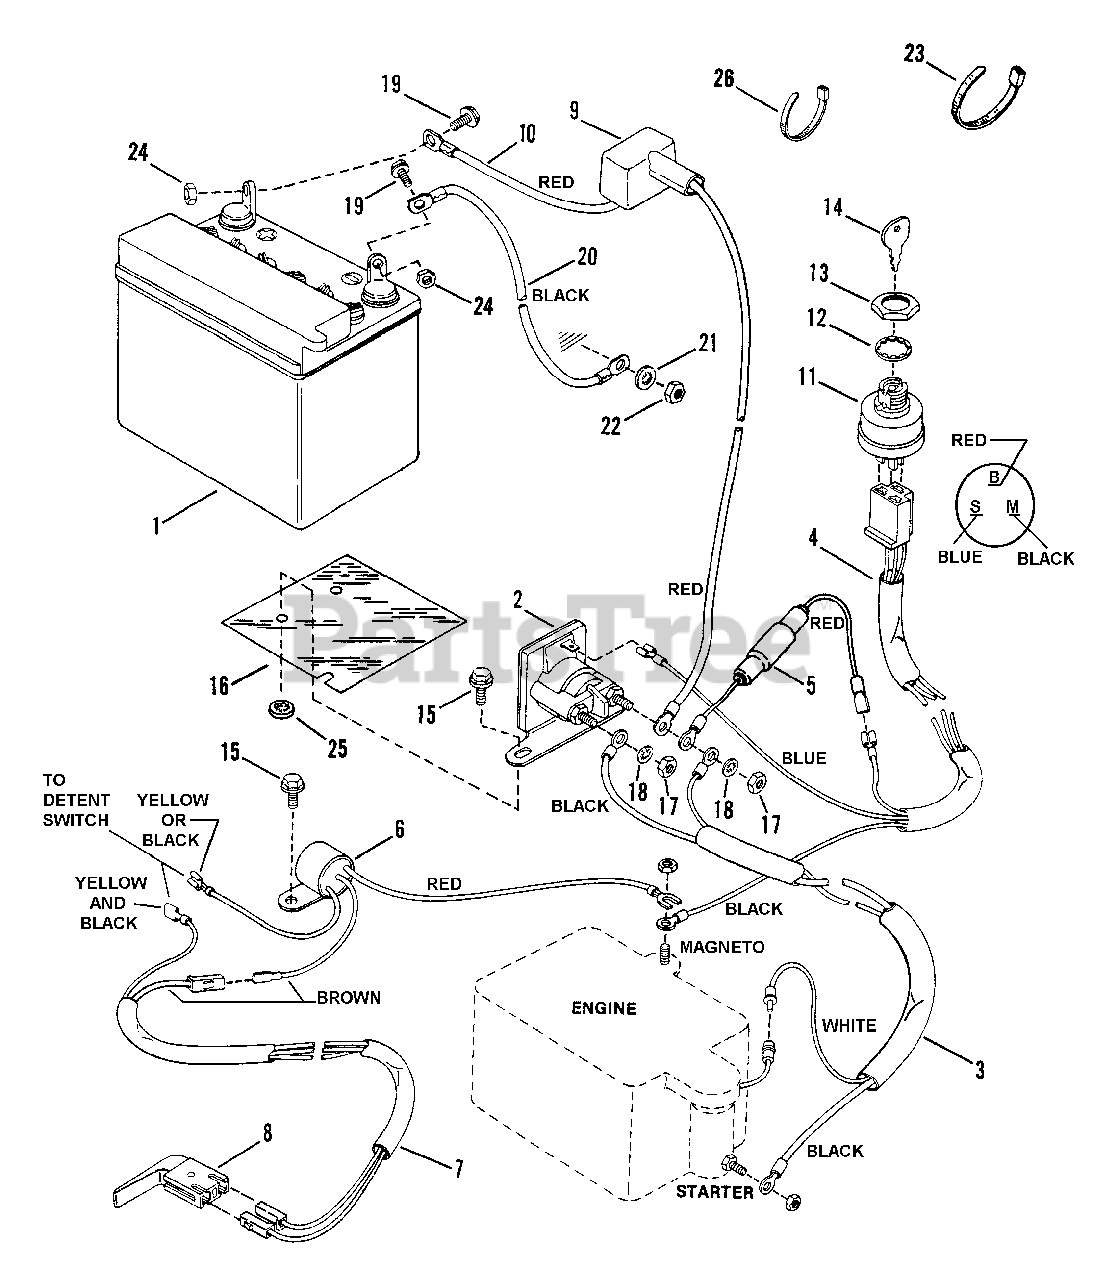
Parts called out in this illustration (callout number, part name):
1	KIT, 12V Dry Charge Battery
2	SOLENOID
3	HARNESS, Starter Wiring w/Square Connector
4	HARNESS, Ignition Wiring
5	HOLDER, Fuse
6	INTERLOCK (Briggs)
7	HARNESS, Deck Interlock Wiring
8	SWITCH, Deck Interlock
9	COVER, Battery Cable
10	CABLE, Positive (Red)
11	SWITCH, Ignition
12	WASHER, 5/8 Internal Tooth Lock
13	NUT, 5/8-32 Hex
14	KEY, Switch (With Cover)
15	SCREW, 1/4-20 x 1/2" Self-Tapping
16	PROTECTOR, Solenoid
17	NUT, 1/4-20 Hex
18	WASHER, 1/4 Internal Tooth Lock
19	SCREW, 1/4-20 x 5/8" Hex Head Cap
20	CABLE, Negative
21	WASHER, 5/16 Internal Tooth Lock
22	NUT, 5/16-18 Hex
23	TIE, 7" Long Cable
24	NUT, 1/4-20 Hex Lock
25	RETAINER, 1/4 Bolt
26	TIE, 2" Long Cable
